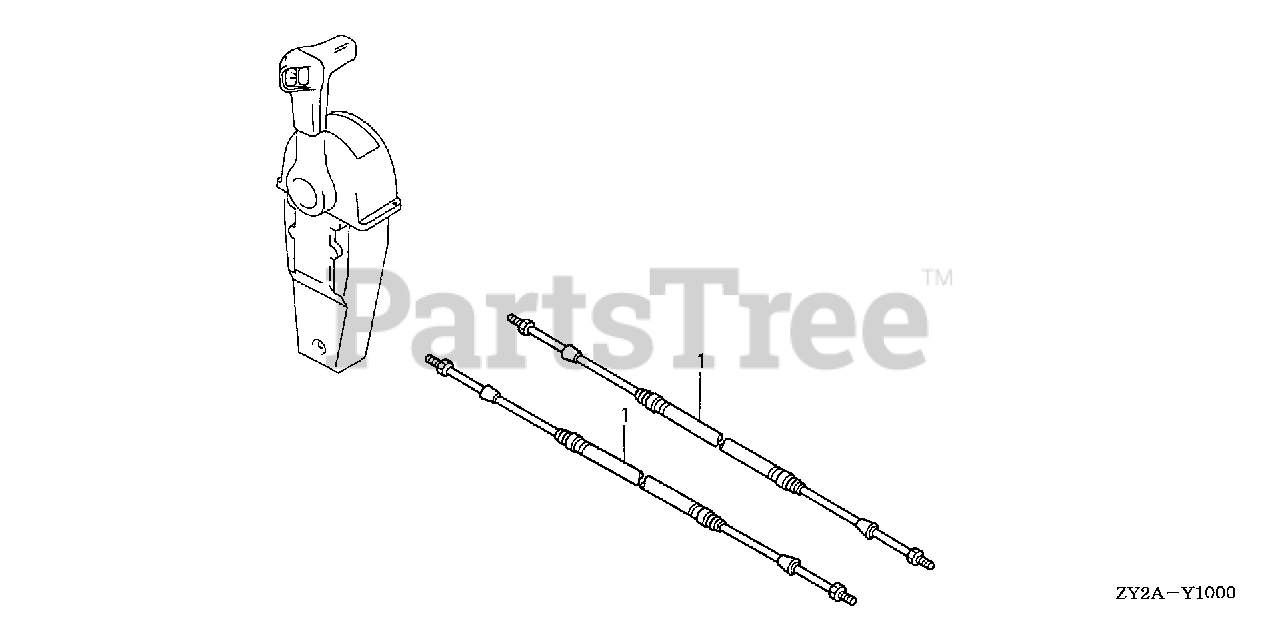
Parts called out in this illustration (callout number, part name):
1	CABLE, REMOTE CONTROL (10') (LOW FRICTION)
1	CABLE ASSY., PUSH-PULL (33C-5FT)
1	CABLE, REMOTE CONTROL (11') (LOW FRICTION)
1	CABLE ASSY., PUSH-PULL (33C-6FT)
1	CABLE, REMOTE CONTROL (12') (LOW FRICTION)
1	CABLE ASSY., PUSH-PULL (33C-7FT)
1	CABLE, REMOTE CONTROL (13') (LOW FRICTION)
1	CABLE ASSY., PUSH-PULL (33C-8FT)
1	CABLE, REMOTE CONTROL (14') (LOW FRICTION)
1	CABLE ASSY., PUSH-PULL (33C-9FT)
1	CABLE, REMOTE CONTROL (15') (LOW FRICTION)
1	CABLE ASSY., PUSH-PULL (33C-10FT)
1	CABLE, REMOTE CONTROL (16') (LOW FRICTION) (NOT AVAILABLE)
1	CABLE ASSY., PUSH-PULL (33C-11FT)
1	CABLE, REMOTE CONTROL (17') (LOW FRICTION)
1	CABLE ASSY., PUSH-PULL (33C-12FT)
1	CABLE, REMOTE CONTROL (18') (LOW FRICTION) (NOT AVAILABLE)
1	CABLE ASSY., PUSH-PULL (33C-13FT)
1	CABLE, REMOTE CONTROL (19') (LOW FRICTION)
1	CABLE ASSY., PUSH-PULL (33C-14FT)
1	CABLE, REMOTE CONTROL (20') (LOW FRICTION) (NOT AVAILABLE)
1	CABLE ASSY., PUSH-PULL (33C-15FT)
1	CABLE, REMOTE CONTROL (21') (LOW FRICTION)
1	CABLE ASSY., PUSH-PULL (33C-16FT)
1	CABLE, REMOTE CONTROL (22') (LOW FRICTION) (NOT AVAILABLE)
1	CABLE ASSY., PUSH-PULL (33C-17FT)
1	CABLE, REMOTE CONTROL (23') (LOW FRICTION)
1	CABLE ASSY., PUSH-PULL (33C-18FT)
1	CABLE, REMOTE CONTROL (24') (LOW FRICTION) (NOT AVAILABLE)
1	CABLE ASSY., PUSH-PULL (33C-19FT)
1	CABLE, REMOTE CONTROL (25') (LOW FRICTION)
1	CABLE ASSY., PUSH-PULL (33C-20FT)
1	CABLE, REMOTE CONTROL (26') (LOW FRICTION)
1	CABLE ASSY., PUSH-PULL (33C-21FT)
1	CABLE, REMOTE CONTROL (27') (LOW FRICTION)
1	CABLE ASSY., PUSH-PULL (33C-22FT)
1	CABLE, REMOTE CONTROL (28') (LOW FRICTION) (NOT AVAILABLE)
1	CABLE ASSY., PUSH-PULL (33C-23FT)
1	CABLE, REMOTE CONTROL (29') (LOW FRICTION)
1	CABLE ASSY., PUSH-PULL (33C-24FT)
1	CABLE, REMOTE CONTROL (30') (LOW FRICTION) (NOT AVAILABLE)
1	CABLE ASSY., PUSH-PULL (33C-25FT)
1	CABLE, REMOTE CONTROL (31') (LOW FRICTION)
1	CABLE ASSY., PUSH-PULL (33C-26FT)
1	CABLE, REMOTE CONTROL (32') (LOW FRICTION) (NOT AVAILABLE)
1	CABLE ASSY., PUSH-PULL (33C-27FT)
1	CABLE, REMOTE CONTROL (33') (LOW FRICTION)
1	CABLE ASSY., PUSH-PULL (33C-28FT)
1	CABLE, REMOTE CONTROL (34') (LOW FRICTION) (NOT AVAILABLE)
1	CABLE ASSY., PUSH-PULL (33C-29FT)
1	CABLE, REMOTE CONTROL (35') (LOW FRICTION)
1	CABLE ASSY., PUSH-PULL (33C-30FT)
1	CABLE ASSY., PUSH-PULL (33C-31FT)
1	CABLE ASSY., PUSH-PULL (33C-32FT)
